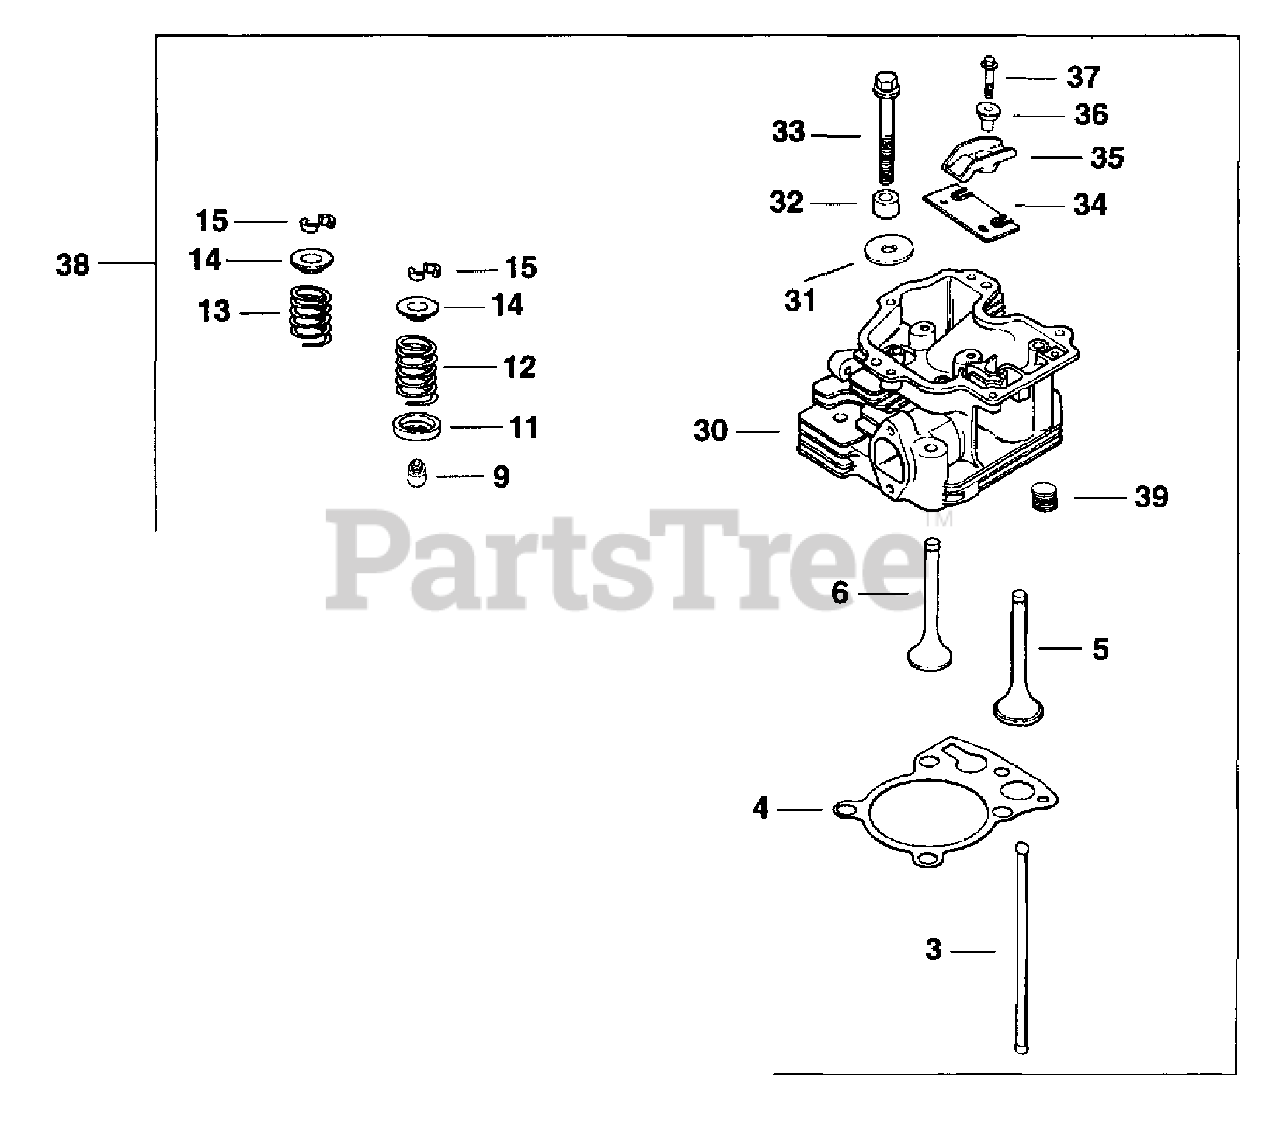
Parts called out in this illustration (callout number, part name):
4	GASKET, CYLINDER HEAD
5	VALVE, INTAKE
5	VALVE, INTAKE (.25 MM)
6	VALVE, EXHAUST
6	VALVE, EXHAUST (.25 MM)
9	SEAL - USE 24 032 05
11	RETAINER, SPRING
13	SPRING
14	RETAINER, VALVE SPRING - USE 25 173 28-S
15	KIT, RETAINER
38	HEAD - USE 12 755 62
39	PLUG, CTSK PIPE 1/8" USE 25 139 60-S
